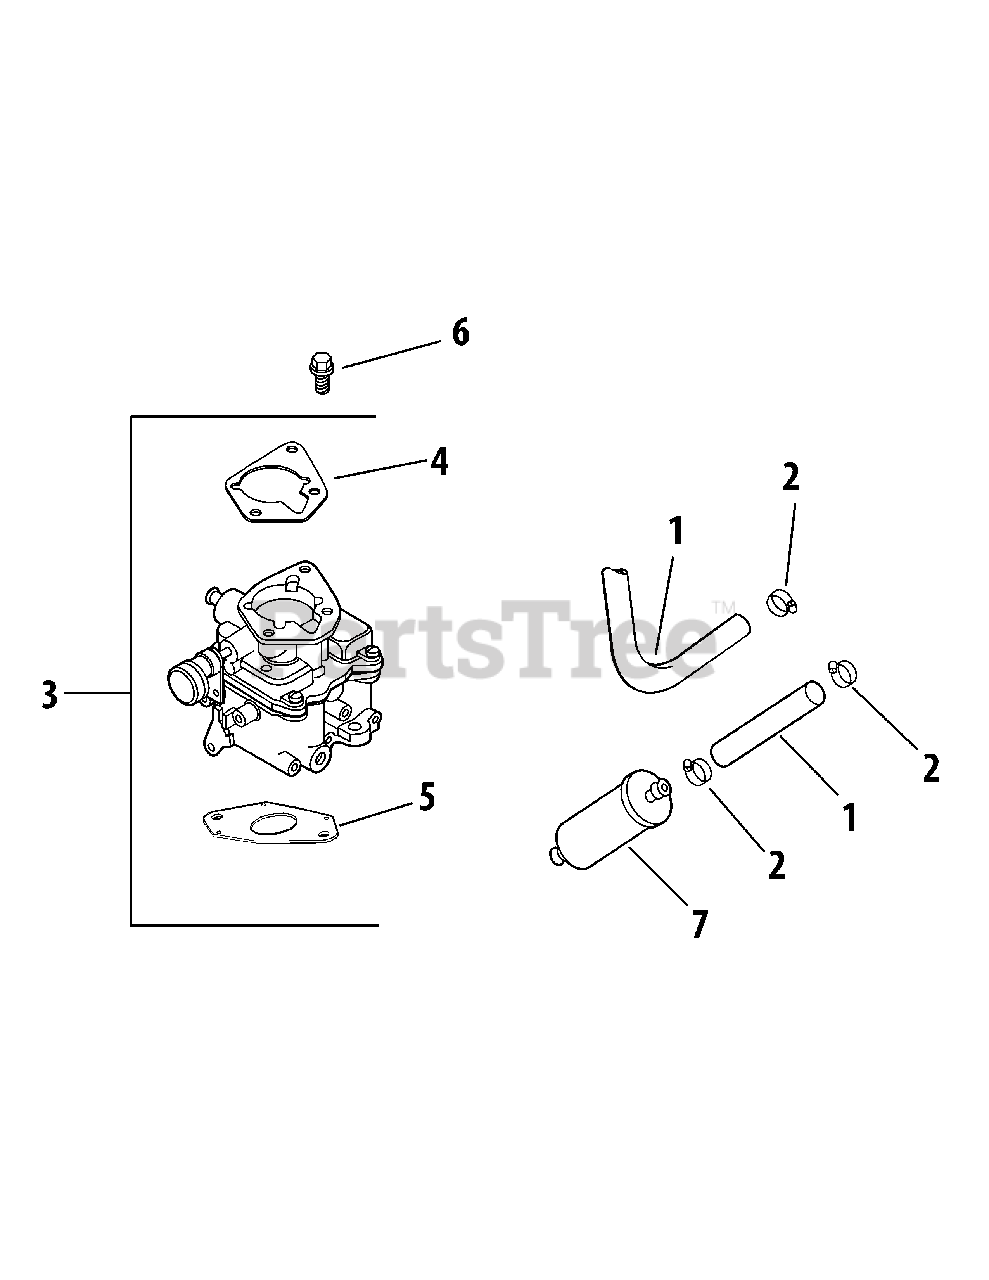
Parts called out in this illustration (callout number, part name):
1	Line, Fuel
2	Clamp, Hose
3	Kit, Carburetor w/Gasket (Includes 4,5)
4	Gasket, Air Cleaner Base
5	Gasket, Carburetor
6	Screw, Hex Flange, M6 x 1.0 x 25
7	Filter, Fuel
